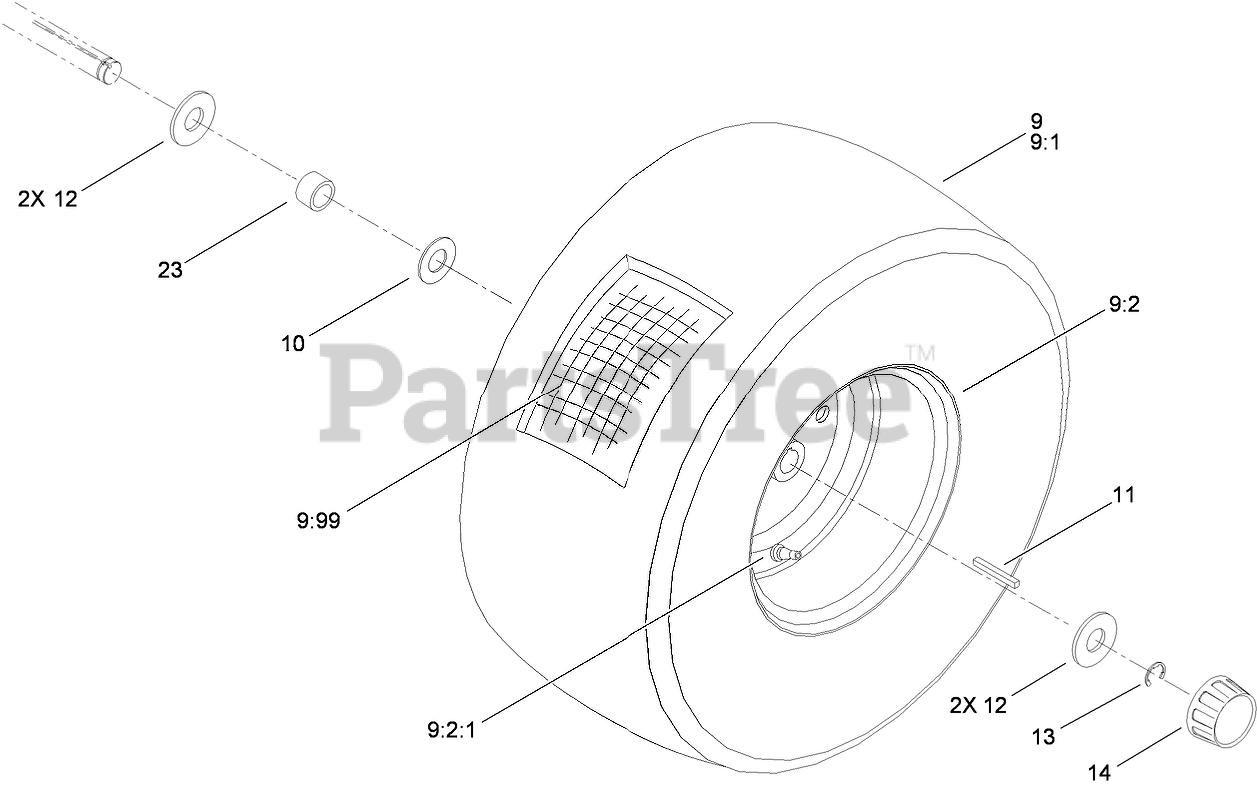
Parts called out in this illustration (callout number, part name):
9	Loose Parts Package
9:1	TIRE
10	WASHER-THRUST
11	KEY-SQUARE
12	WASHER-PLAIN
13	E-RING
14	CAP-HUB
23	SPACER-WHEEL
